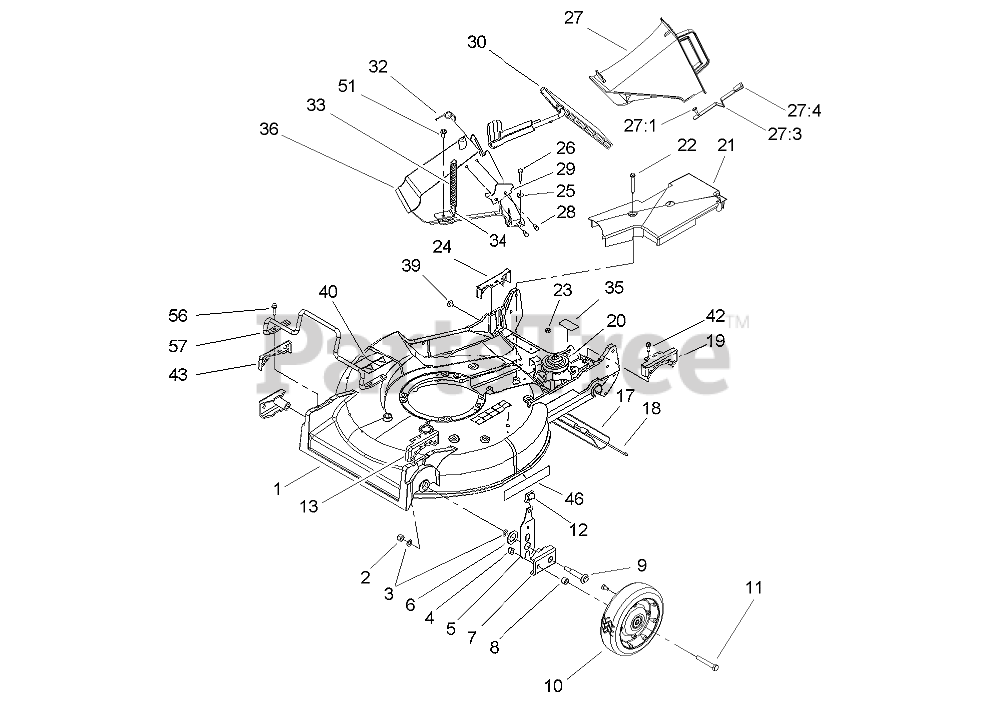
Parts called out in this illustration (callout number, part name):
1	HOUSING
2	NUT-LOCK
3	WASHER
4	NUT-LOCK, CONE
5	FRONT SPRING ARM ASM
6	WASHER-THRUST
7	ARM-PIVOT, FRONT
8	SPACER-WHEEL
9	BOLT-WHEEL
10	WHEEL AND TIRE ASM
11	SCREW-HH
12	KNOB-ARM
13	QUADRANT-FRONT, LH
17	SHIELD-TRAILING
18	ROD-SHIELD
19	QUADRANT-REAR, LH
20	GEAR CASE ASM
21	COVER-BELT
22	SCREW-HHFTF
23	NUT-LOCK, NI
24	QUADRANT-REAR, RH
25	WASHER-FLAT
26	SCREW-HH
27	DISCHARGE PLUG ASM
27:1	RIVET-HEAD, FLAT
27:3	LATCH-PLUG, DISCHARGE
27:4	GRIP-LATCH
28	SCREW-PLASTITE
29	LATCH-PLATE
30	DISCHARGE DOOR ASM
32	RETAINER-DOOR
33	SPRING-DOOR
34	BRACKET-SPRING
35	DECAL-GREASE
36	TUNNEL-DISCHARGE
39	SCREW AND WASHER ASM
40	DECAL-DANGER
42	SCREW-HWHTF
43	QUADRANT-FRONT, RH
51	SCREW-HWH
56	SCREW-HWHTF
57	GUARD-ENGINE
